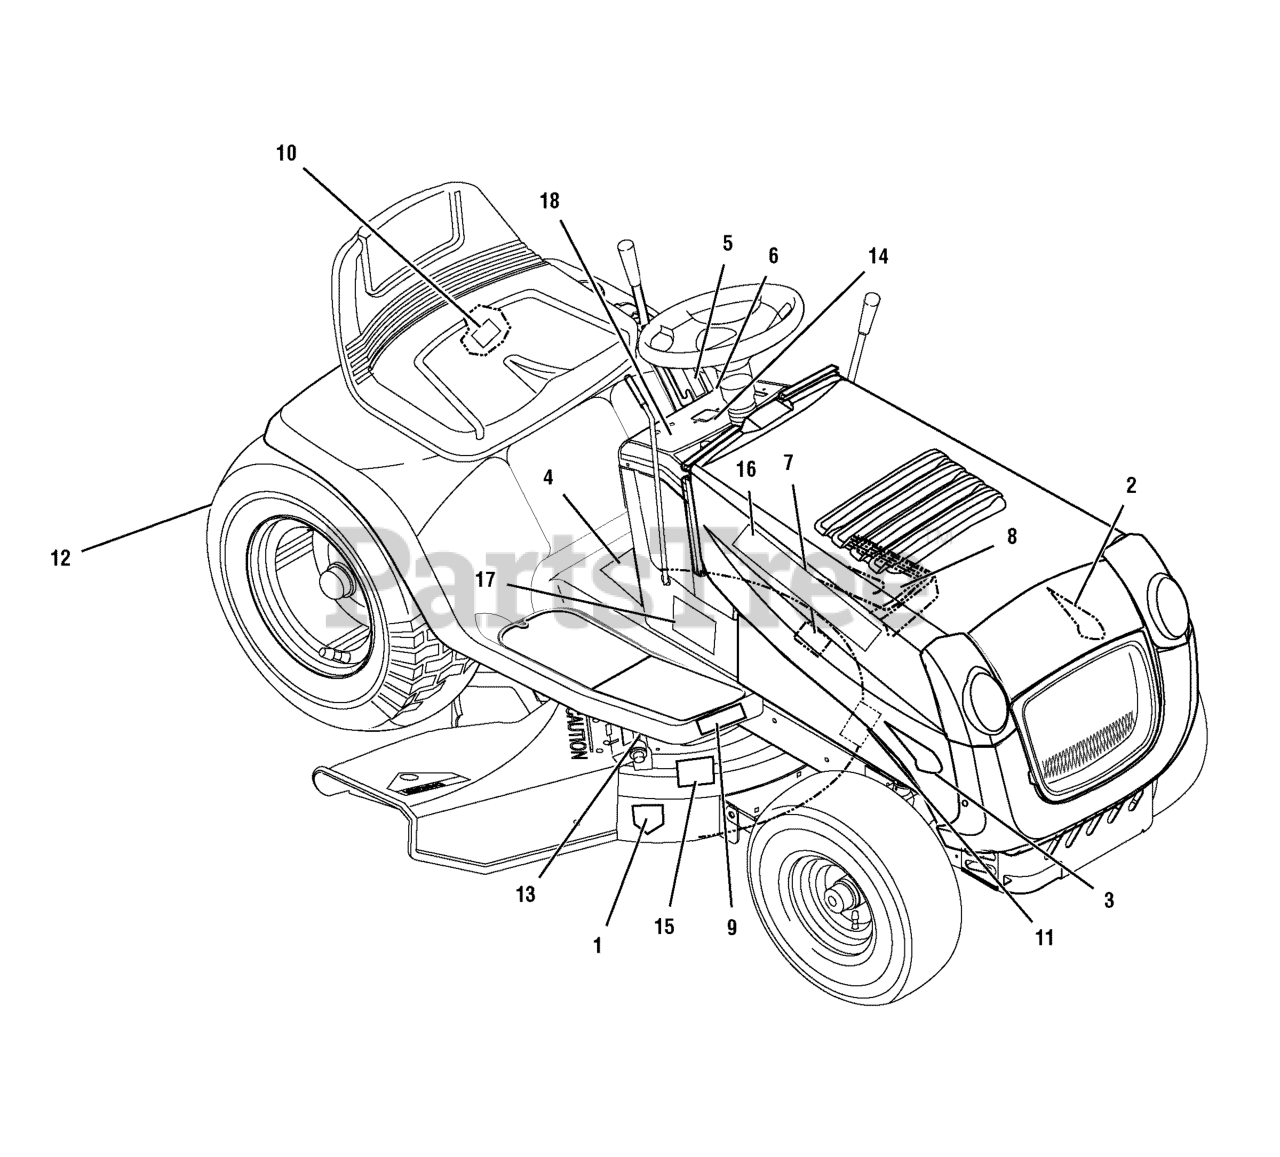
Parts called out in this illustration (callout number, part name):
1	DECAL, Cut Finger Symbols
2	DECAL, 155/102 L.H.
3	DECAL, 155/102 R.H.
4	DECAL, Warning Export
5	DECAL, 7 Position Cut Height
6	DECAL, Deck Level
7	DECAL, No Step Export
8	DECAL, Brake/Clutch
9	DECAL, Hydro Drive
10	DECAL, Auto Drive Dump Valve
11	DECAL, Heat Shield Warning
12	DECAL, Warning Load Limit Export
13	DECAL, Warning Pinch Point
14	DECAL, Dash/Symbols W1
15	DECAL, 100db Export
16	DECAL, Sentinel by Murray R.H. & L.H.
17	DECAL, B&S Logo
18	DECAL, Gas Gauge
